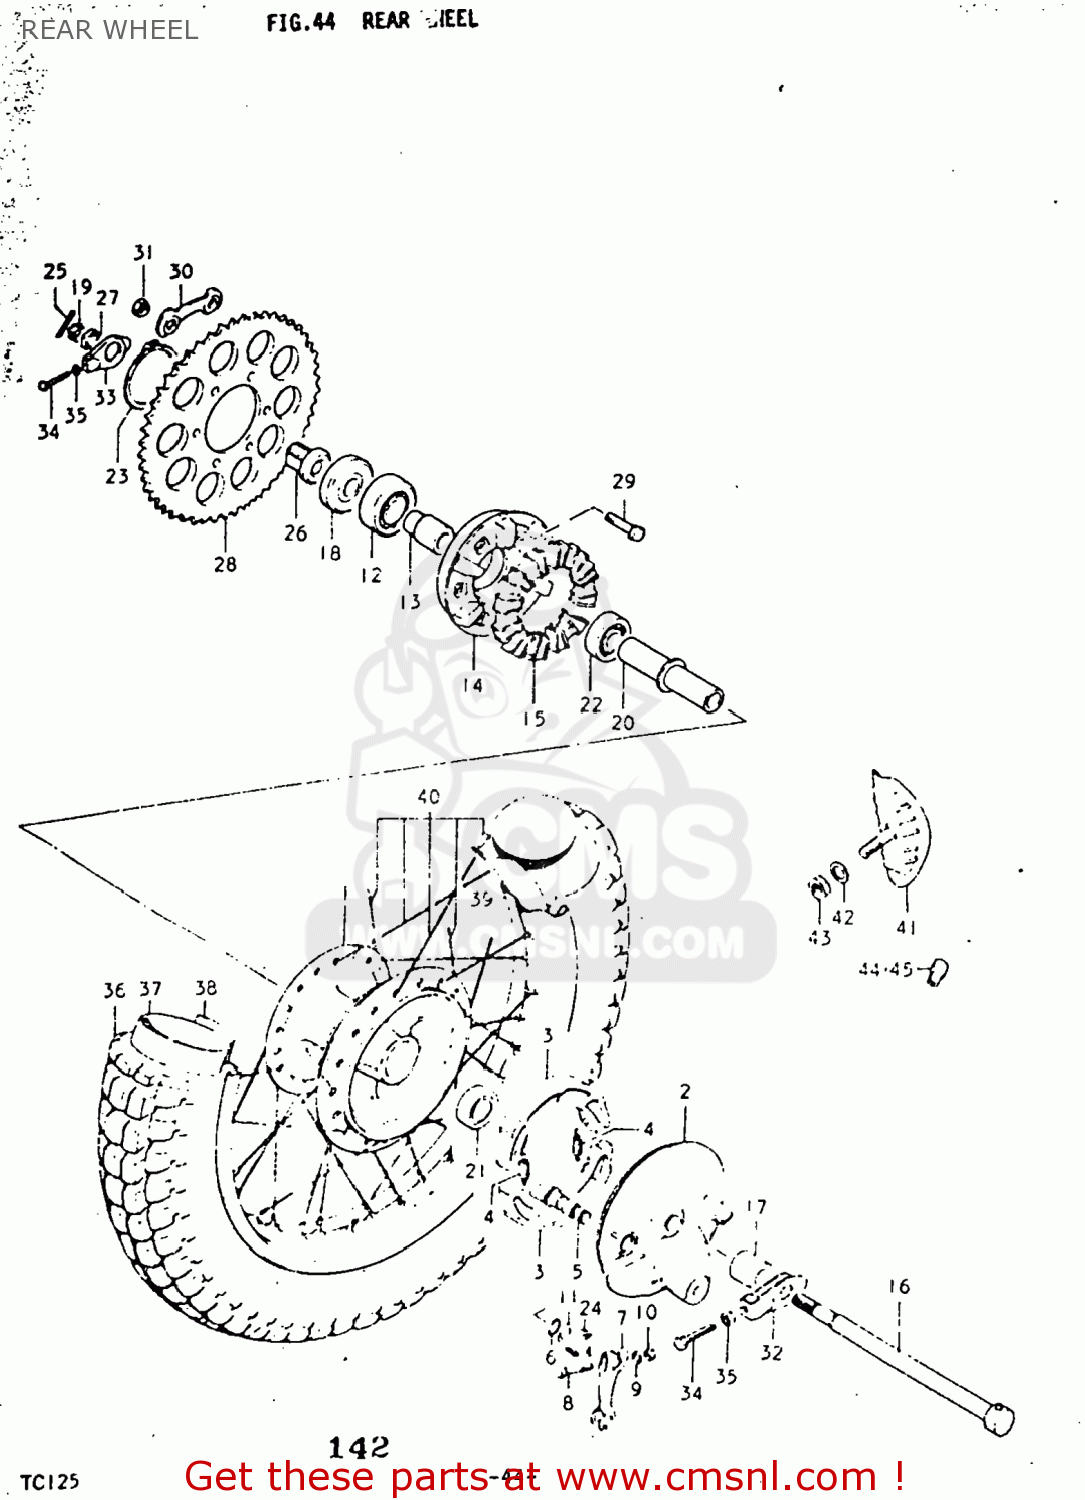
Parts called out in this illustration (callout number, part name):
1	HUB,REAR
2	PANEL,REAR HUB
3	SHOE,BRAKE
4	SPRING(L:34)
5	CAM,FRONT BRAKE
6	O RING(D:2.5,ID:11.4)
7	LEVER,REAR BRAKE CAM
8	BOLT
9	WASHER
10	NUT
11	WASHER(12.5X20X1)
12	BEARING
13	SPACER,REAR HUB BEARING
14	DRUM,REAR SPROCKET MOUNT
15	ABSORBER,RR WHEEL HUB SHOCK
16	AXLE,REAR
17	SPACER
18	SPACER,RR AXLE,L
19	NUT 12MM
20	SPACER
21	BEARING
22	BEARING
23	CIRCLIP
24	SPRING
25	COTTER PIN
26	SPACER,REAR AXLE
27	NUT
28	SPROCKET,REAR
29	BOLT(8X32)
30	WASHER
31	NUT
32	ADJUSTER,CHAIN
33	ADJUSTER,CHAIN
34	BOLT
35	NUT
36	TIRE
37	TUBE ASSEMBLY,WHEEL,INNER
38	PROTECTOR,WHEEL,INNER
39	RIM,REAR WHEEL
40	SPOKE SET,REAR
41	STOPPER,BEAD
42	WASHER
43	NUT
44	BALANCER,WHEEL
45	BALANCER,WHEEL (50G)
